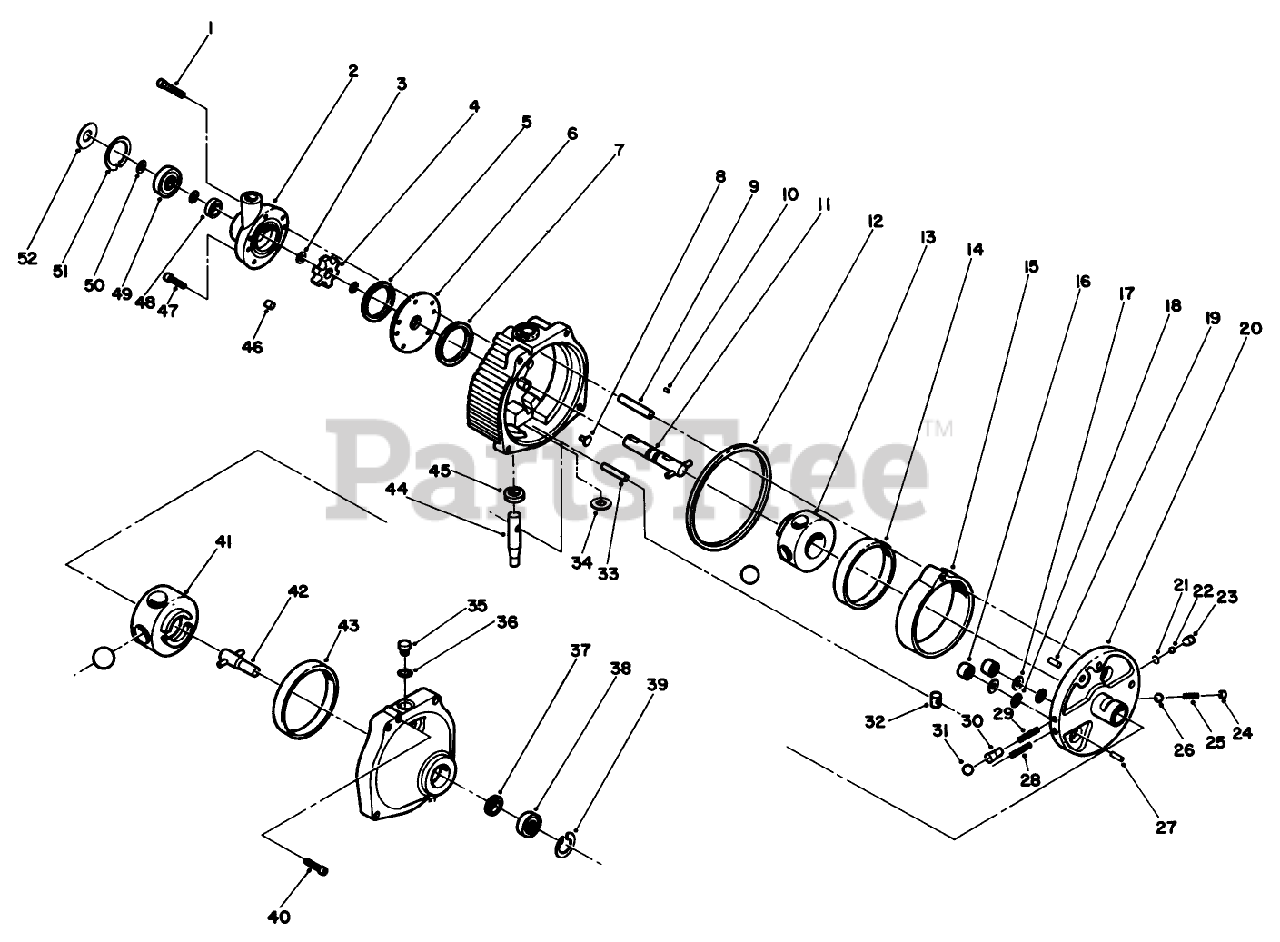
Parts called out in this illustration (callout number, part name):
1	CAPSCREW
2	Charge Pump (Incl. Ref. #48)
3	Snap Ring
4	CARRIER
6	PLATE
8	BUTTON
11	SHAFT
13	ROTOR
14	Pump Race
15	Cam Ring Assy. (Incl. Ref. #14)
16	PISTON
18	O-RING
20	Pintle Assembly (Incl. Ref. #16-19 & 21-31)
25	SPRING
28	Acc. Valve Spring (Lower)
29	SPRING
32	INSERT
33	Dowel
34	Control Shaft Washer
35	"O" Ring Plug Sub-Assembly (Incl. Ref. #36)
36	O-RING
37	Oil Seal
38	Bearing
40	Socket Head Capscrew
41	ROTOR
42	SHAFT
44	SHAFT KIT
45	SEAL-OIL
47	SCREW-HH
48	SEAL-OIL
49	BEARING
51	RING
52	Grass Shield
